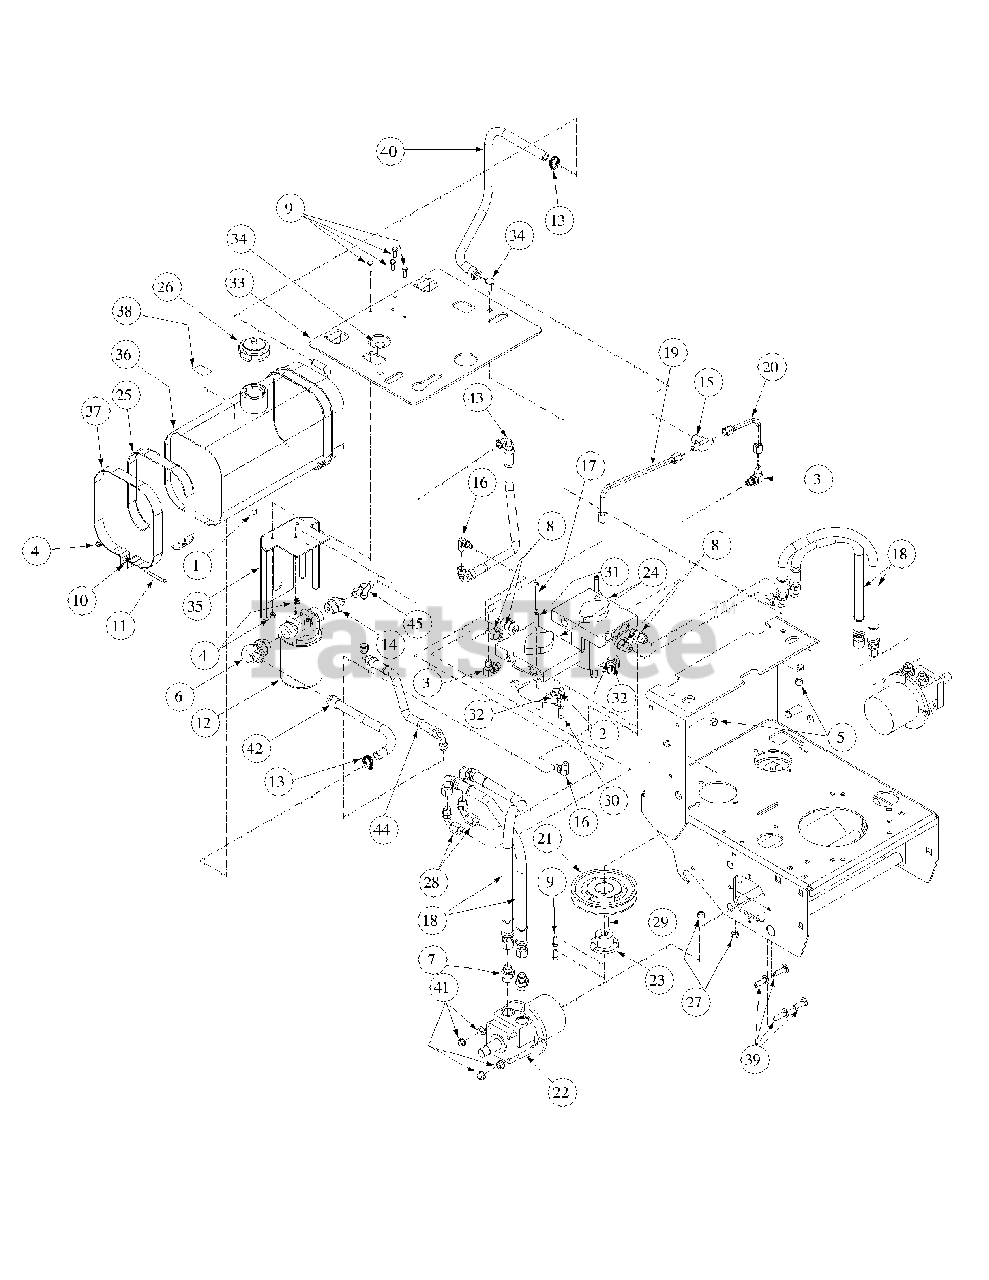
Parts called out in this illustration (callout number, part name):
1	Plug, 1/4"
2	Cap Screw, Standard, 3/8-16 x 1-1/4
3	Fitting, Aeroquip
4	Lock Nut, 1/4-20
5	Lock Nut, 3/8-16
6	Elbow 90° 1/2 x 3/4
7	Fitting, Aeroquip
8	Fitting, Aeroquip
9	Cap Screw, 1/4-20 x 3/4
10	Hex Nut, 1/4-20
11	Machine Screw, 1/4-20 x 2, Zinc
12	Filter Head 3/4
12	Oil Filter
13	Clamp Wormgear, 5/16-7/8
14	Straight Connector 1/2 x 3/4
15	Fitting Aeroquip
16	Fitting, Aeroquip
17	Cap Screw, Socket Head, 1/4-20 x 2-1/2 Zinc
18	Hydro Hose Assembly, Reverse Pressure
19	Hydraulic Line, Pump Return Long
20	Hydraulic Line, Pump Return Short
21	Deck Pulley
22	Hydraulic Motor, Wheel
23	Bushing, 15mm Bore, Split, Type "D"
24	Pump Hydro BDP10L117
25	Pad, Oil Tank
26	Cap, Hydraulic Oil Tank
27	Lock Nut, 3/8-16
28	Fitting Aeorquip
29	Pump Key
30	Nut, Pump Release
31	Spacer, Pump Release
32	Washer, Idler
33	Fuel Tank, Mounting Plate
34	Carriage Bolt, 3/8-16 x 2
35	Filter Guard
36	Oil Tank w/Neck
37	Oil Tank Strap
38	Oil Label, 20W-50
39	Carriage Bolt, 3/8-16 x 1.25
40	Hose Assembly
40	Hose Hydraulic 22"
41	Hex Nut, Flange Lock, 3/8-16
42	Hose, Filter to Tank
43	Hose, Filter to Left Pump
44	Hose, Filter to Right Pump
45	Fitting, Aeroquips
